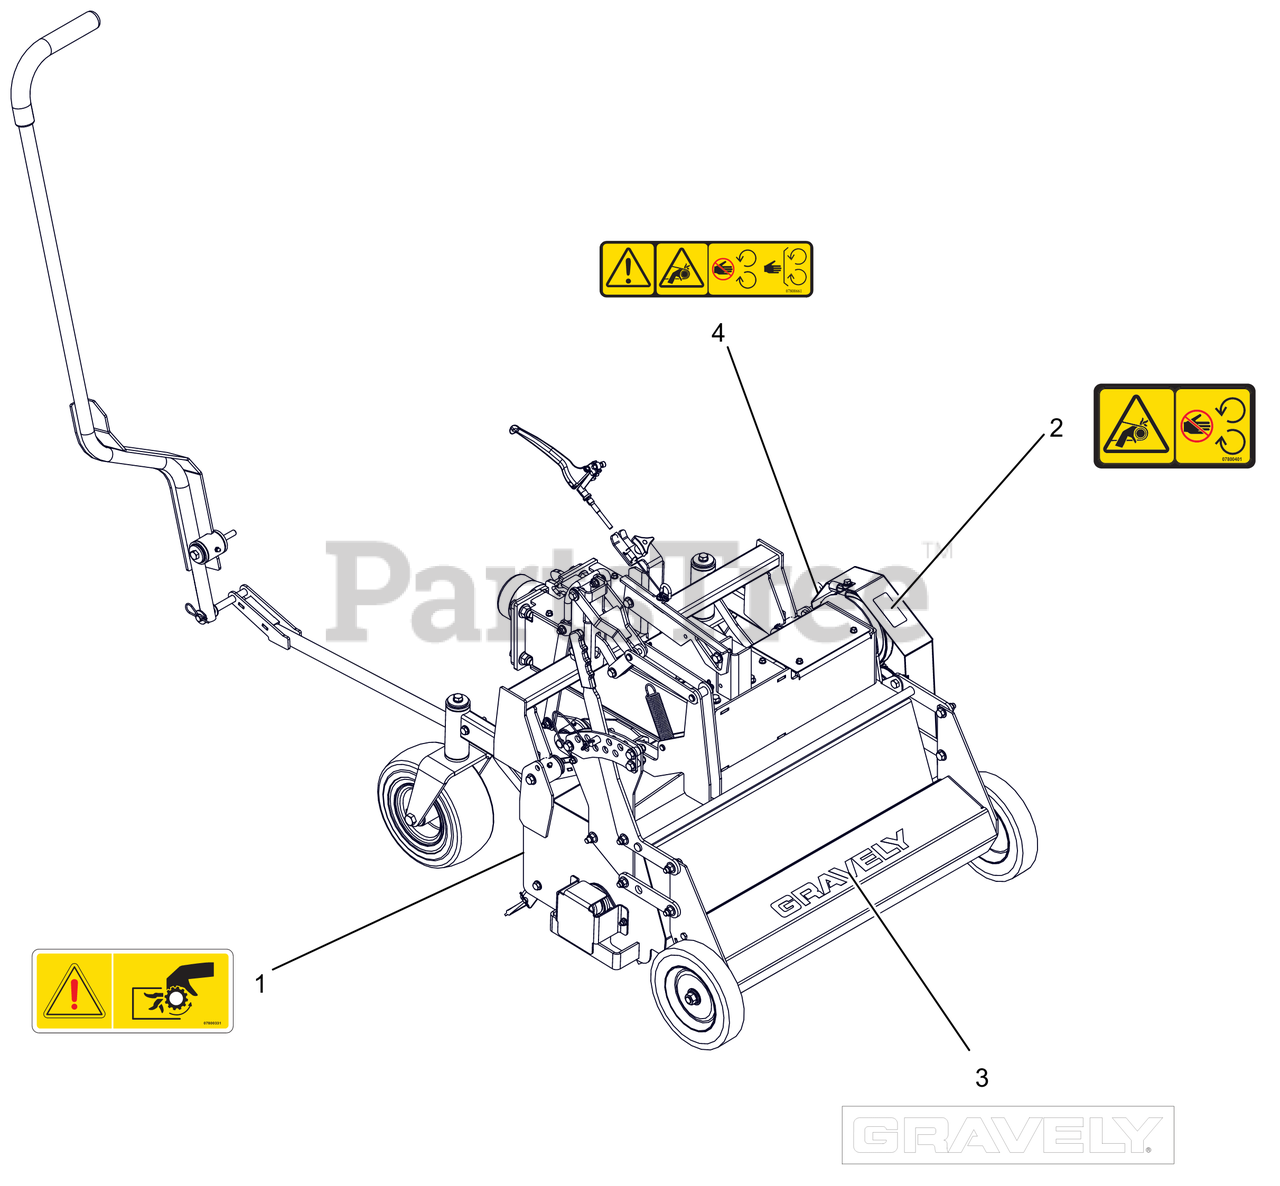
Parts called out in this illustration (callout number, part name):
1	DECAL, PTO WARNING
2	DECAL, SAFETY - GUARDING
3	DECAL, 13.5" GRAVELY LOGO
4	DECAL, SHIELD REMOVED
